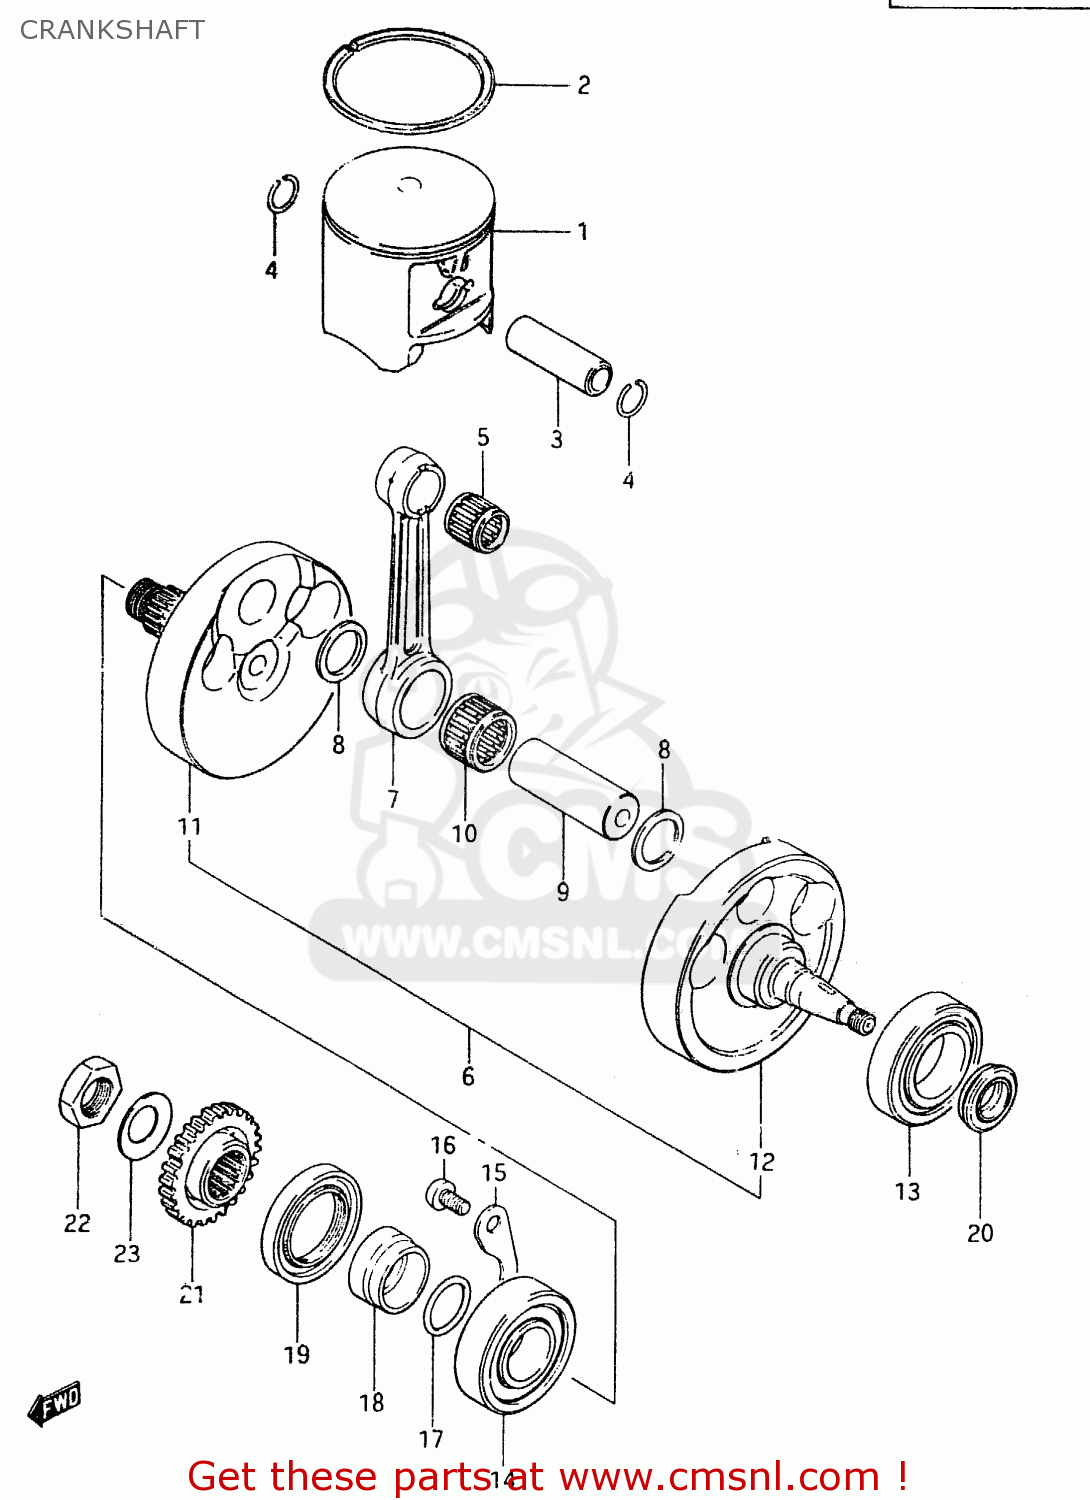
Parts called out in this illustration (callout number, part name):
1	PISTON
2	RING,PISTON
3	PIN,PISTON (18MM)
4	CIRCLIP,PISTON PIN
5	BEARING(18X23X22)
6	CRANKSHAFT ASSEMBLY
7	ROD,CONNECTING
8	WASHER(26X32X1.5)
9	PIN,CRANK
10	ROLLER BEARING (26X33X2
11	CRANKSHAFT,RIGHT
12	CRANKSHAFT,LEFT
13	BEARING
14	BEARING
15	PLATE,CRANKSHAFT OIL S
16	SCREW
17	O RING(D:2.4,ID:27.7)
18	SPACER,PRIMARY DRIVE GEAR
19	SEAL,OIL(37X62X9)
20	SEAL,OIL(19.6X37X8)
21	GEAR,PRIMARY DRIVE
22	NUT (20MM)
23	WASHER
